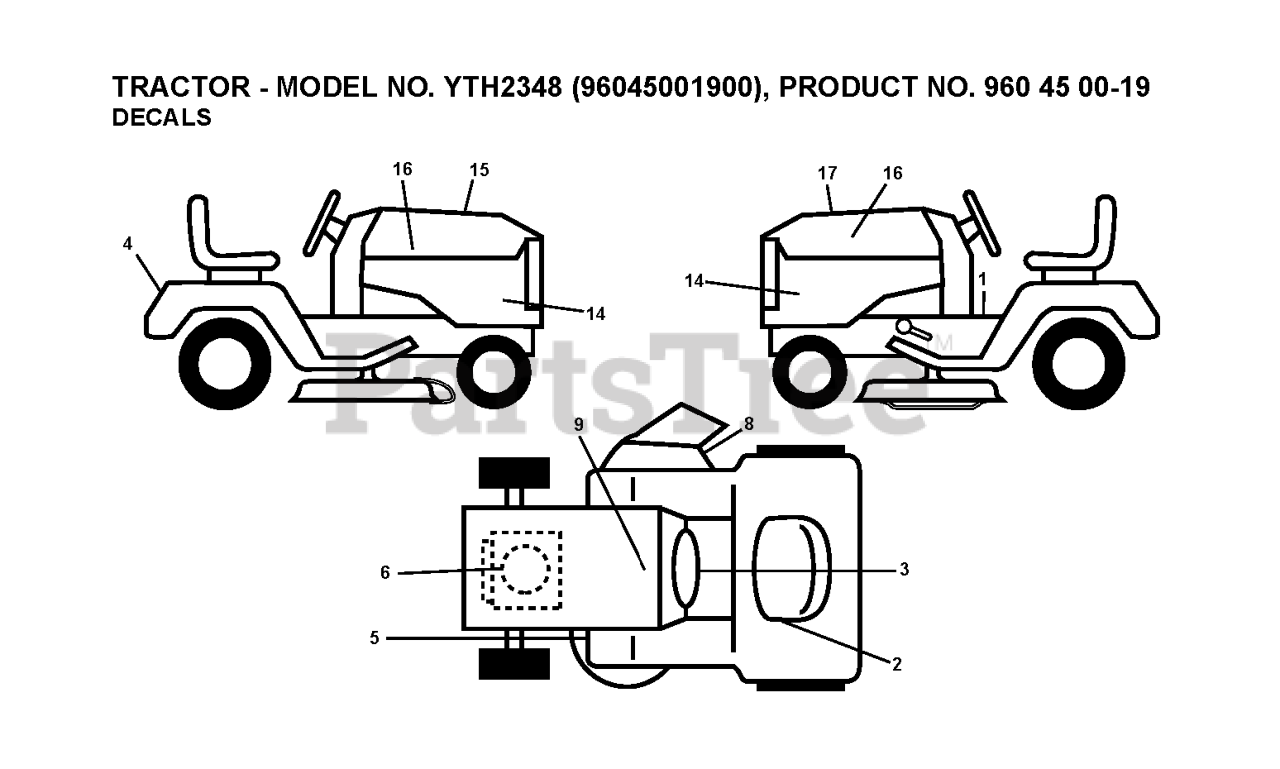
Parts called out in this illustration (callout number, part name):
1	DECAL.WARN.START.INSTRUCTIONS
2	DECAL,ETHANOL E85 WARNING
3	DECAL, WARNING SPARK ARRESTOR
4	DECAL.FENDER
5	DECAL.MOWER
6	DECAL, ENG. HP
8	DECAL.MOWER.SCH.48/54
9	DECAL BTRY SYMBOLS
14	DECAL, PANEL SIDE
15	DECAL.WARNING.CUST.RESP.E85.
16	DECAL.HOOD.LOGO.ORANGE.HUSQVAR
